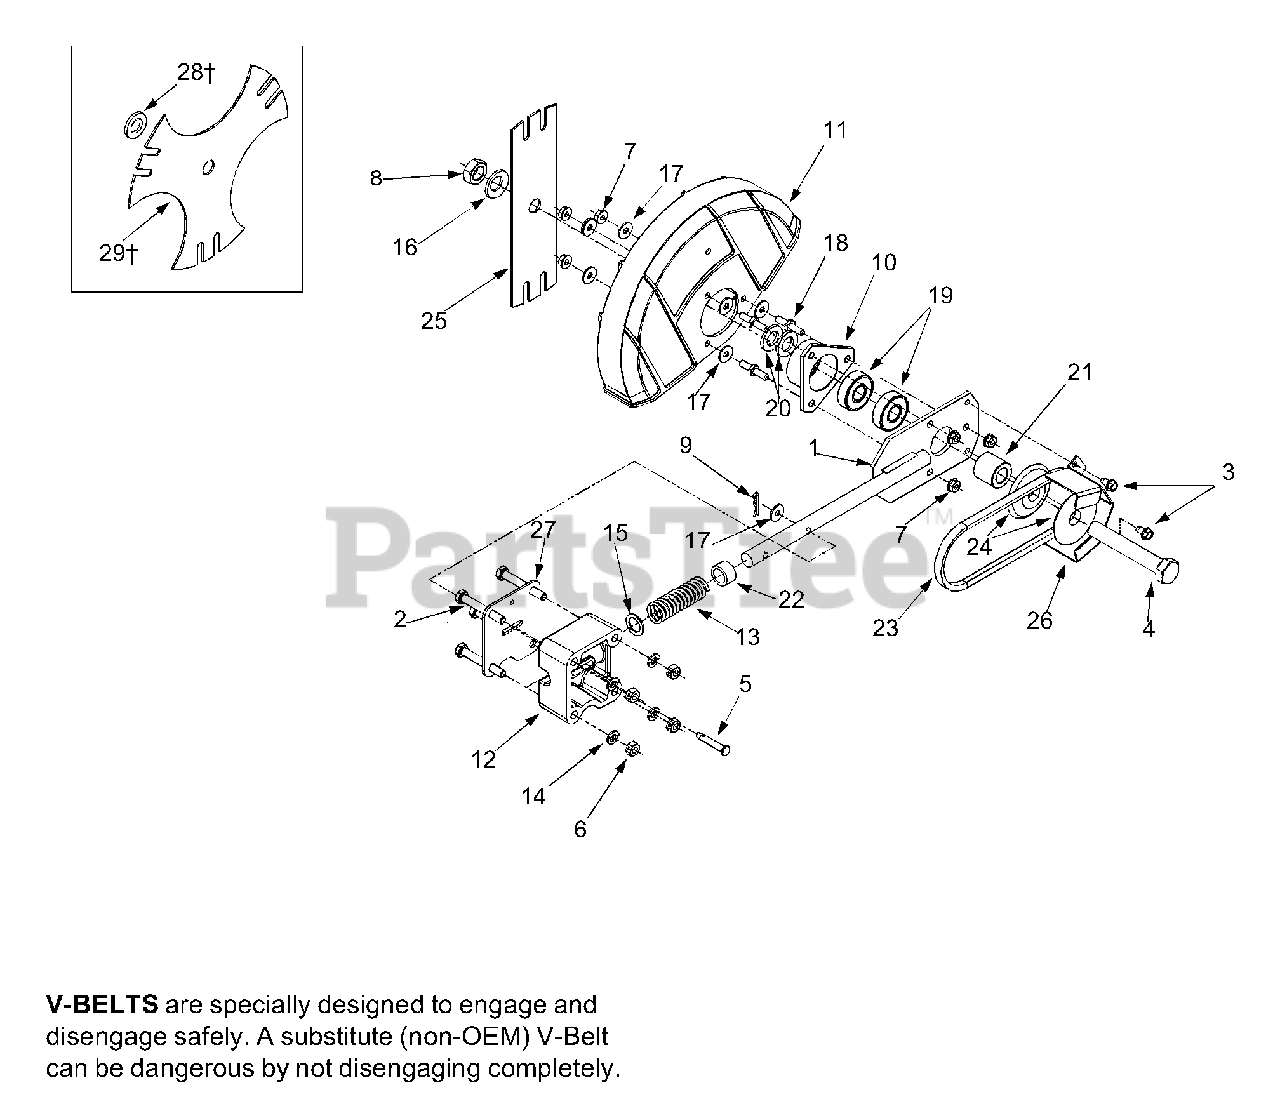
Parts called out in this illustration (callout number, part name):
1	Blade Plate Assembly
2	Hex Screw, 5/16-18
3	Self-tapping Screw, 1/4-20
4	Hex Screw, 5/8-18
5	Clevis Pin
6	Hex Lock Nut, 5/16-18
7	Hex Flange Nut, 1/4-20
8	Jam Nut, 5/8-18
9	Cotter Pin
10	Bearing Cup
11	Blade Guard
12	Bearing Block
13	Compression Spring
14	Lock Washer
15	Flat Washer
16	Bell Washer,.63 ID x 1.2 OD
17	Flat Washer,.260 x.72
18	Pin, 1/4-20
19	Bearing,.625 ID x 1.57 OD
20	Flat Washer
21	Spacer,.63 x 1.12 x 1.06
22	Spacer,.632 ID x.875 OD
23	Belt
24	Sheave
28	Flat Washer
